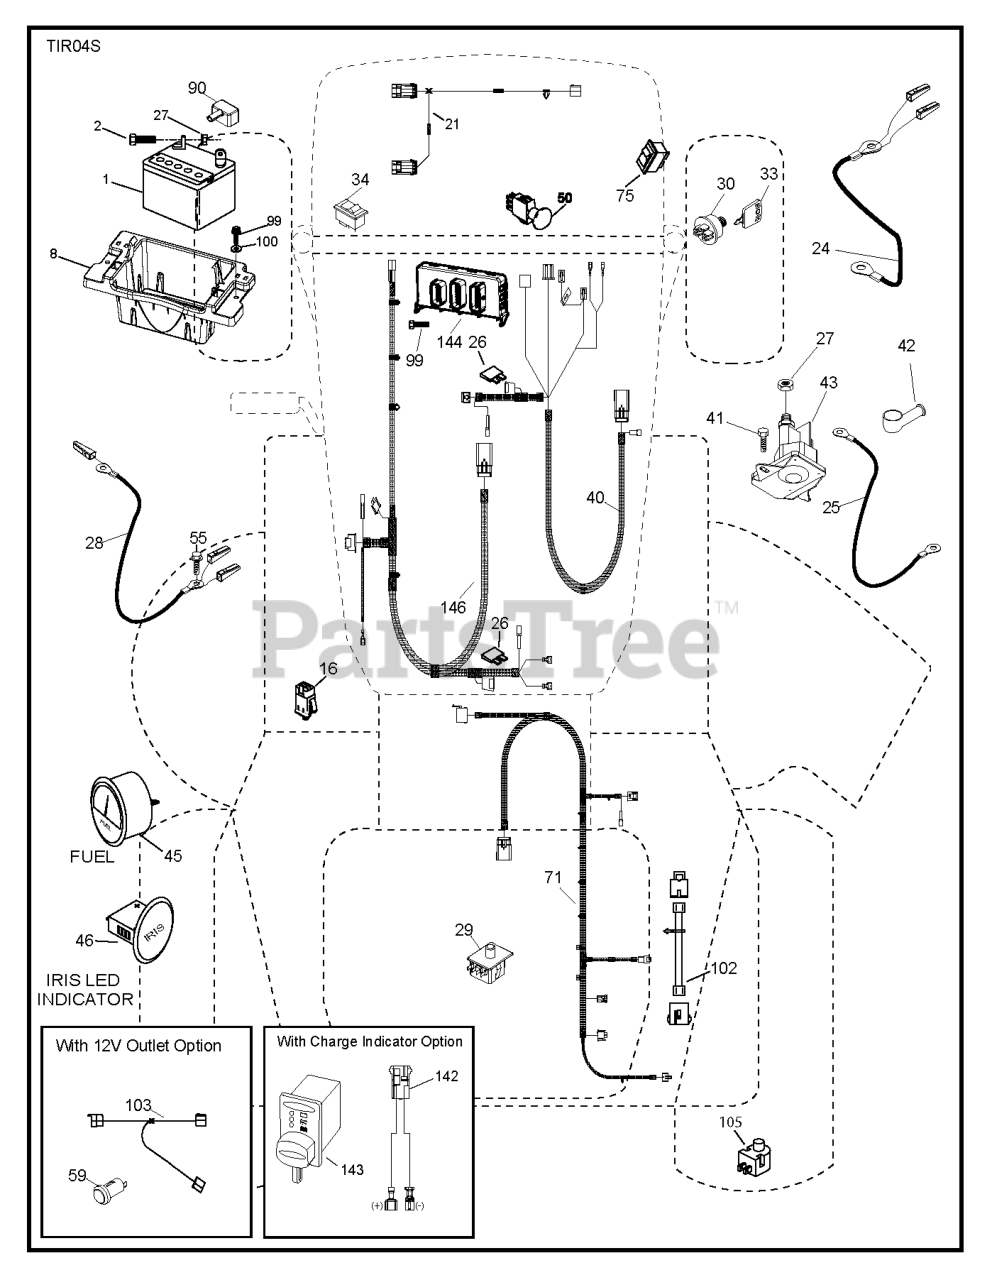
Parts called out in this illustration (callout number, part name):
1	Battery 12 Volt 25 Amp
2	BOLT.HEX.1/4.X.3/4.DICHROMATE
8	TRAY.BATTERY BOX.FRONT
16	SWITCH INTERLOOK PUSH-IN
21	HARNESS.LIGHT W/4152J BULBS
24	CABLE.FRBATT.W/WIRE.8GA.8
25	CABLE.STARTER.8GA.17.5
26	FUSE 20AMP
27	NUT
28	CABLE.GROUND.21"BLK.8GA.90T
29	SWITCH.SEAT.DELTA.OPC.
30	SWITCH.IGN.DELTA.W.LGH.ROS
33	KEY.CHAIN.BLISTER.PACK.GEN.USA
40	HARNESS.IGN.DSH.W112V.WPORTWIR
41	SCREW
42	TERMINAL COVER
43	SOLENOID.W/BRASS.PLUNGER
45	GAUGE.AMMETER.SILVER/WHITE
46	GAUGE.HOUR.METER.SILVER/WHITE
50	RP.PTO.SWITCH.8 TERMINAL.BLACK
55	SCREW 5/16"
71	HARNESS-CHASSIS SUB
75	REVERSE SWITCH
90	COVER.TERMINAL.BATTERY
99	SCREW HEXWSHR 1/4-20X3/4
100	WASHER
102	HARNESS PIGTAIL PCH TEX ROS
105	REVERSE SWITCH
144	CONTROL.UNIT.RIDE.ON.IRIS.BASE
146	WIRING ASSY ENGINE, IRIS, 300,
